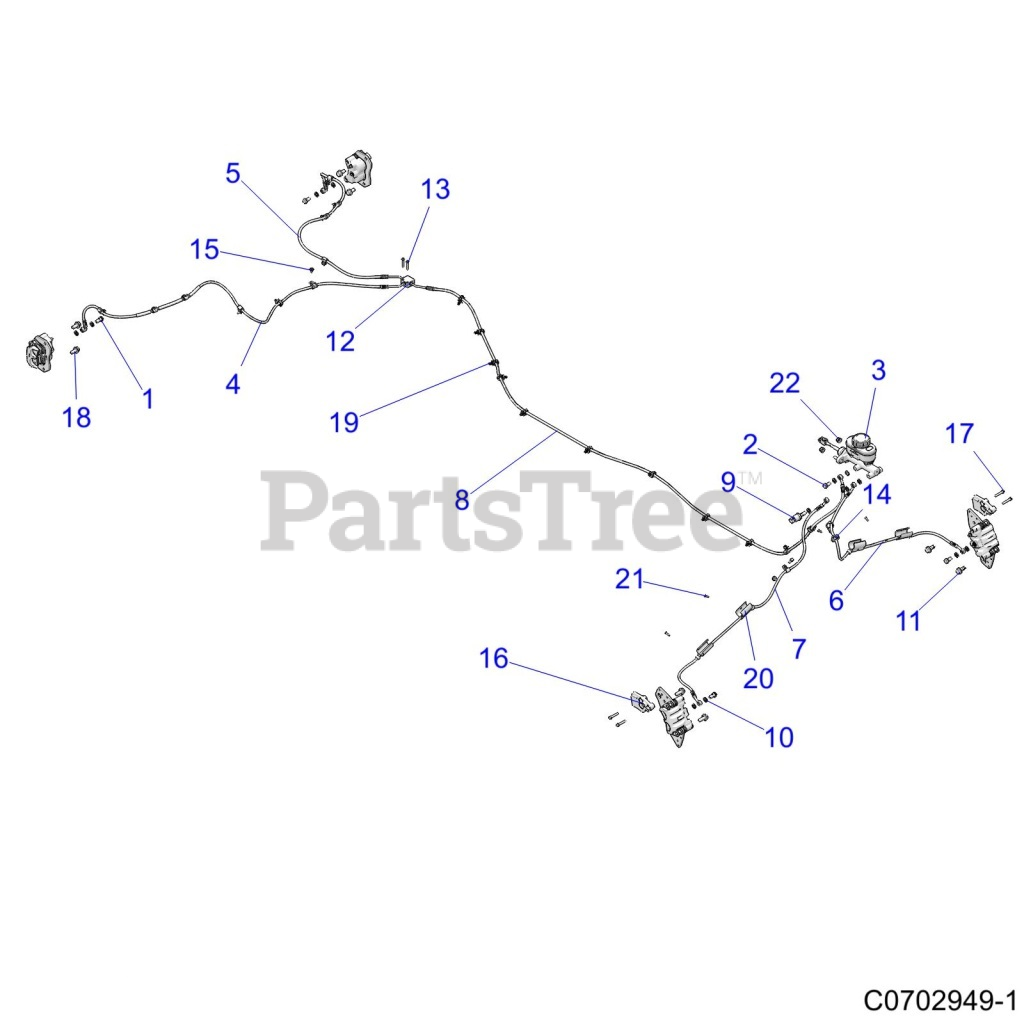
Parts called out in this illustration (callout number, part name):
1	BOLT-BANJO,10MMX1.00
2	BOLT-BANJO, 10MM X 1.25-6G
3	ASM-M/C-T-FLANGE,3/4 BORE
4	LINE-BRK,RR,60,45F,90SB,120°JF
5	LINE-BRK,RL,41.1,45F,90SB,290J
6	LINE-BRK,FL,35.2,45B,20B,120°J
7	LINE-BRK,FR,41.7,70B,20B,85°J
8	LINE-BRK,M/T,105.4,20B,30F,263
9	SWITCH-BRK,M10X1.25,DBL,SEALED
10	SEAL-STAT-O-3/8,70EP
11	BOLT-M10X1.25X25,HXFLG,W/PATCH
12	FITTING-TEE,BRAKE
13	SCR-10-24X1.25TFM PN TRX TRI-Y
14	CLIP-ROUTING
15	SCREW(10)
16	SCRAPER-BRAKE,FRONT
17	SCR-HXFL,M6X1.0X35,W/PATCHLOK
18	BOLT-M10X1.25X20,HXFLG-OLV D
19	CLIP-NYLON,C,FIR-TREE
20	RETAINER-BRAKE LINE,1"
21	POP RIVET(50)
22	NUT-M8X1.25,FLG,NYLOC-OLIVE D
